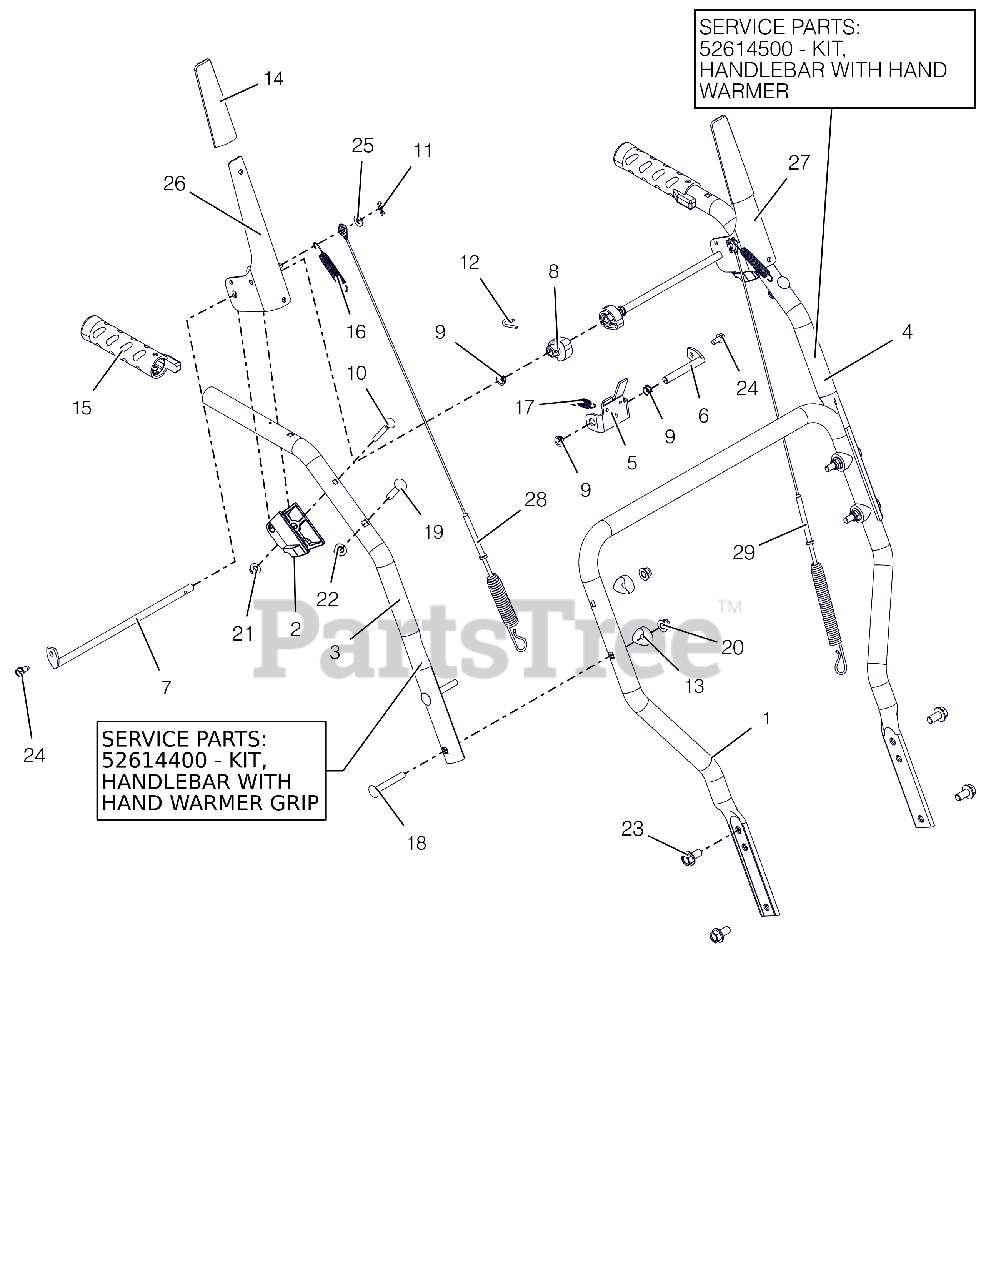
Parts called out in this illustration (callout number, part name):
1	HANDLEBAR, LOWER
2	BLOCK, CLUTCH PADDLE
3	HANDLEBAR, UPPER - RH
3	KIT, HANDLEBAR HW RH
4	HANDLEBAR, UPPER - LH
4	KIT, HANDLEBAR HW LH
5	BRACKET, INTERLOCK ARM
6	ROD, PIVOT - INTERLOCK
7	ROD, PADDLE MOUNT - PRO
8	CAM, INTERLOCK
9	BUSHING, POLYLINER-.38 SNAPIN
10	BLT-RDHDXLSQNK .25-20X2.0 G5YZ
11	PIN-HAIR INT .06X.18X.77
12	PIN, SPRING CLIP
13	SPACER, HANDLEBAR
14	SLEEVE, CLUTCH PADDLE-GRAY
15	GRIP,HEATED HANDLE-GRAY
16	SPRING, EXTENSION
17	SPRING-EXT .047X.438X1.45
18	@BLT-RDHDSQNK .31-18X2.25 G5YZ
19	@BLT-RDHDSQNK .31-18X1.50 G5YZ
20	@NUT-LK-NYL-FLG .31-18 YWZC
21	@NUT-LK-CTR-FLG .25-20 YWZC
22	@NUT-LK-TOP-FLG .31-18 YWZC
23	BLT-SERHFWH .38-16X.75 YWZC
24	SCR-TAP .25-20X.50 HWH TR YWZ
25	@WSHR-FL-STL.281X.62X.065 YWZC
26	LEVER, CLUTCH-RH
27	LEVER, CLUTCH-LH
28	CABLE, AUGER (DELUXE & PRO)
29	CABLE, UPPER TRACTION
